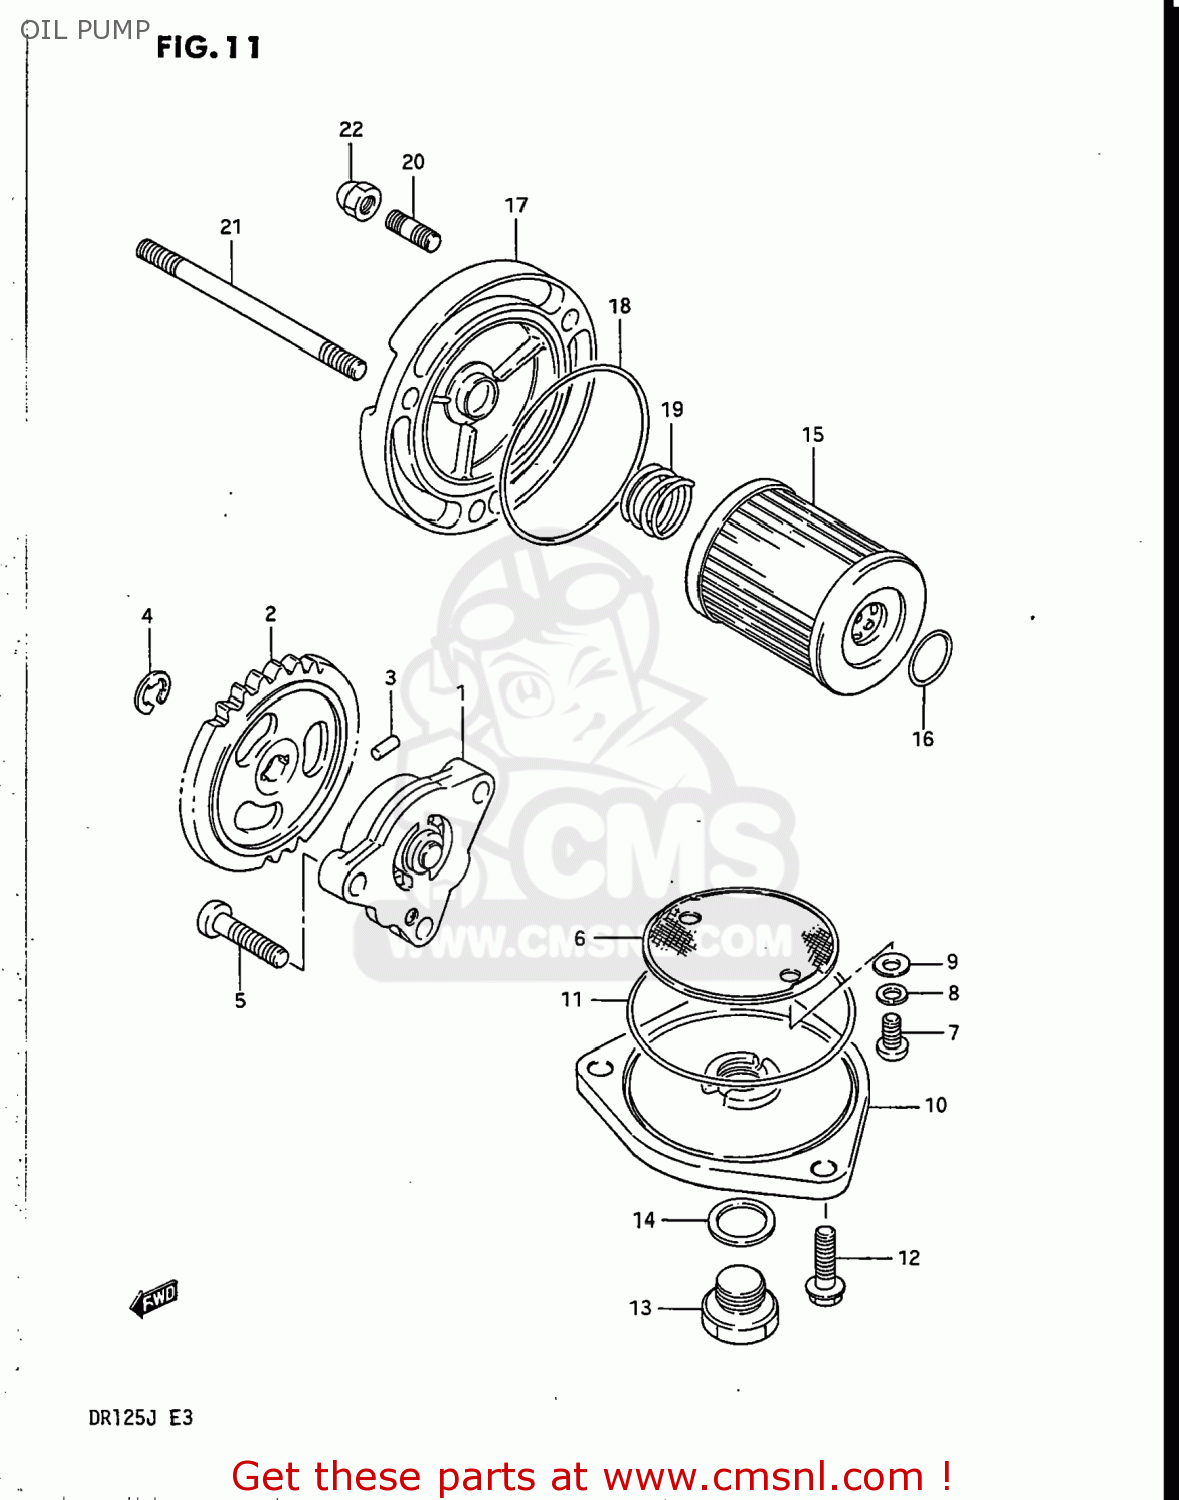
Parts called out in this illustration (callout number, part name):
1	PUMP ASSY,ENGINE OIL
2	GEAR,OIL PUMP DRIVEN (N
3	PIN(2.5X11.8)
4	E RING 6MM
5	SCREW
6	STRAINER,ENGINE OIL
7	SCREW 5X12
8	LOCK WASHER
9	WASHER
10	CAP,OIL STRAINER
11	O RING(D:2.4,ID:60.5)
12	BOLT
13	PLUG
14	GASKET(14X19.2X2) (NAS)
15	FILTER,OIL
16	O RING(D:1.9,ID:13)
17	CAP,OIL FILTER
18	O RING(D:2.4,ID:52.6)
19	SPRING
20	STUD 6X12
21	STUD BOLT
22	NUT 6MM
